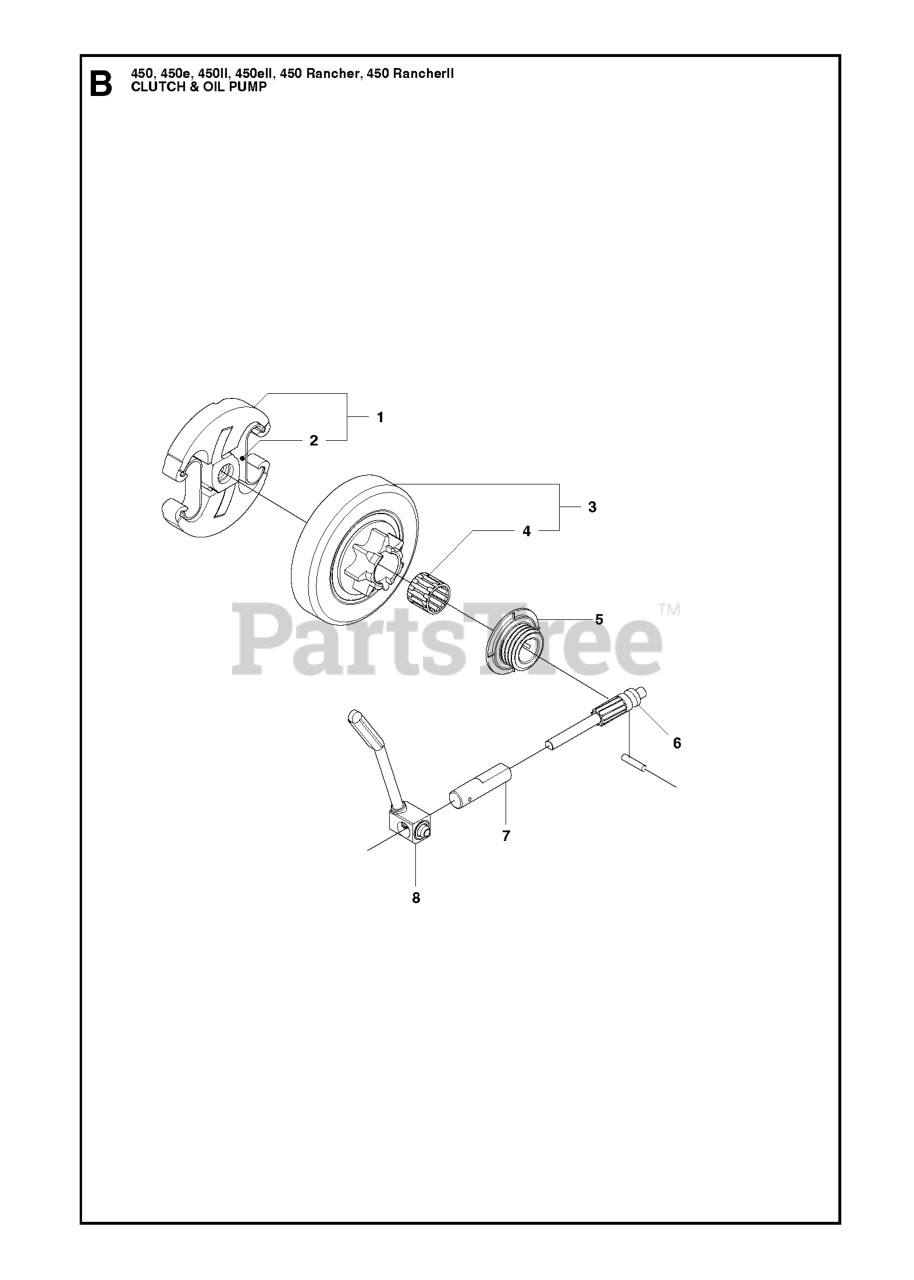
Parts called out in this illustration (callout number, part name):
3	CLUTCH DRUM
4	NEEDLE BEARING
5	GEAR WHEEL OIL PUMP
6	PISTON PUMP
7	PUMP CYLINDER
